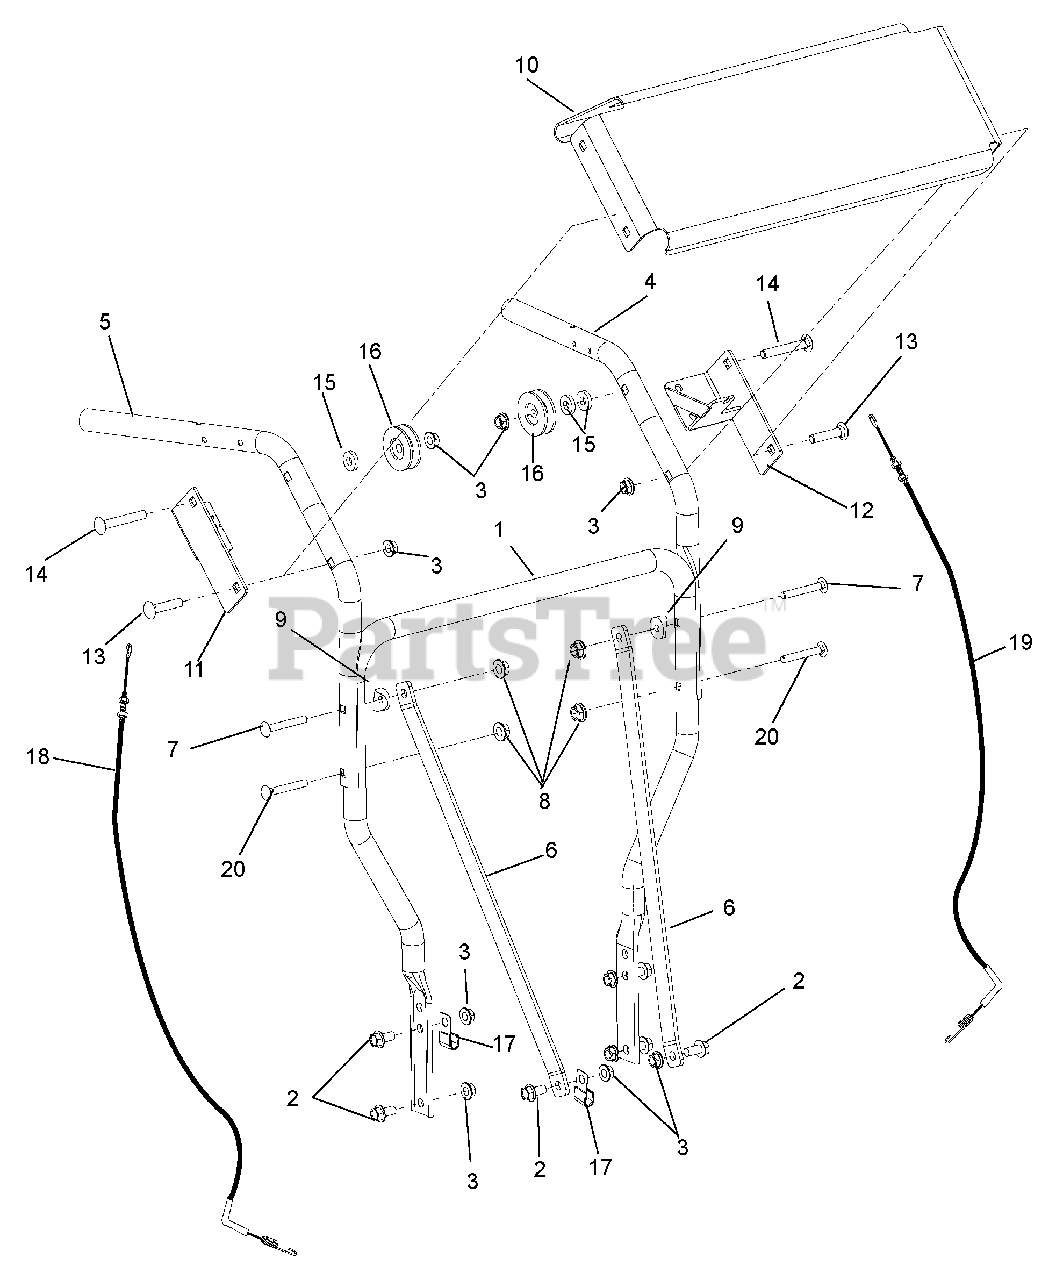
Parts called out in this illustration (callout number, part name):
1	Handlebar, Lower
2	Bolt, Screw Hex Flanged Whiz Lock Head .38-16 x .75
3	Nut, Locking Top Flange .38-16
4	Handlebar, Upper Left Hand
5	Handlebar, Upper Right Hand
6	Bracket, Handlebar Brace
7	Bolt, Round Head Square Neck .31-18 x 2.25
8	Nut, Nyloc Flange .31-18
9	Spacer, Handlebar
11	Mount, Brake Cable Pillow
12	Mount, PTO Cable
13	Bolt, Round Head Square Neck .38-16 x 1.75
14	Bolt, Round Head Square Neck .38-16 x 2.50
15	Washer, Flat Steel .390 x .88 x .18
16	Idle, 3L Front Side .38 x 1.875
18	Cable, Brake Control
19	Cable, PTO Control
20	Bolt, Round Head Square Neck .312-18 x 1.75
